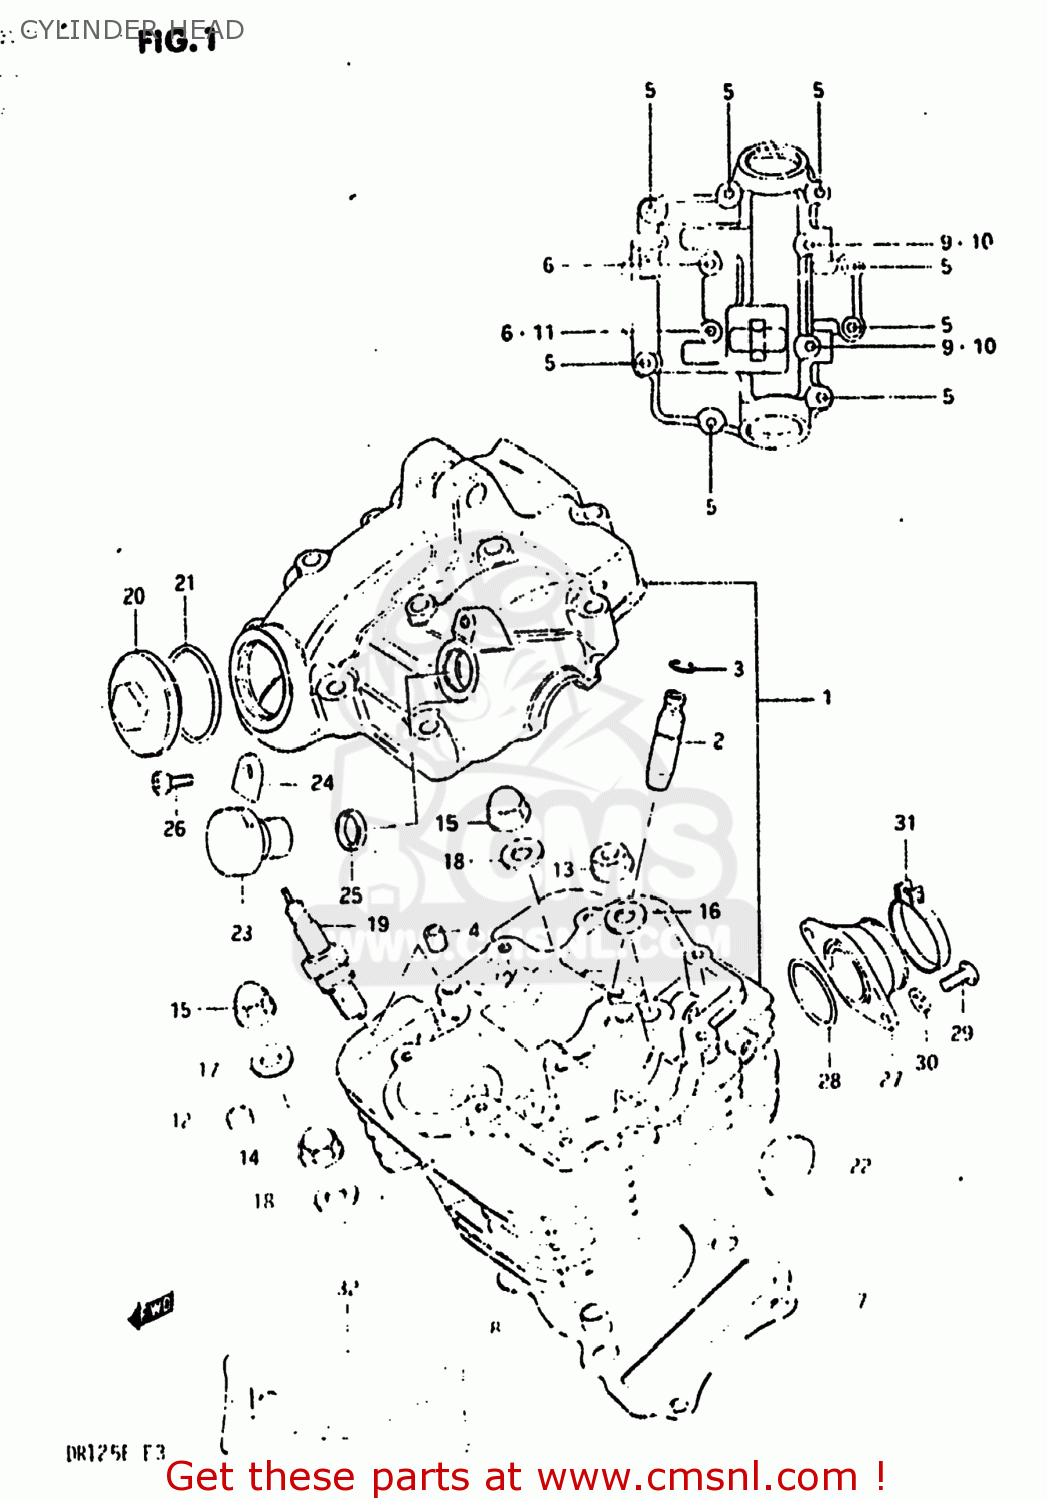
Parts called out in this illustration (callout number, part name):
1	HEAD ASSEMBLY,CYLINDER
2	GUIDE,VALVE
3	RING,SNAP
4	PIN(6.2X8X11)
5	BOLT
6	BOLT ,6X60
7	GASKET,CYLINDER HEAD (NAS)
8	PIN
9	STUD 6X25
10	NUT
11	GASKET
12	PAD,CYLINDER HEAD
13	NUT
14	NUT
15	NUT (8MM)
16	WASHER(8.5X19X2.3)
17	WASHER (8.5X19X2.3)
18	GASKET (NAS)
19	SPARK PLUG D8EA
20	CAP,INSPECTION
21	O RING(D:3,ID:29.5)
22	PLUG(OD:22.5)
23	PLUG,TACH GEAR SLEEVE HOLE
24	PLATE,TACH DRIVE GEAR SLEEVE
25	SEAL,TACHOMETER DRIVEN
26	SCREW(5X12)
27	PIPE,INTAKE
28	O RING(D:2.4,ID:31.7)
29	SCREW
30	LOCK WASHER
31	CLAMP
32	GASKET SET
